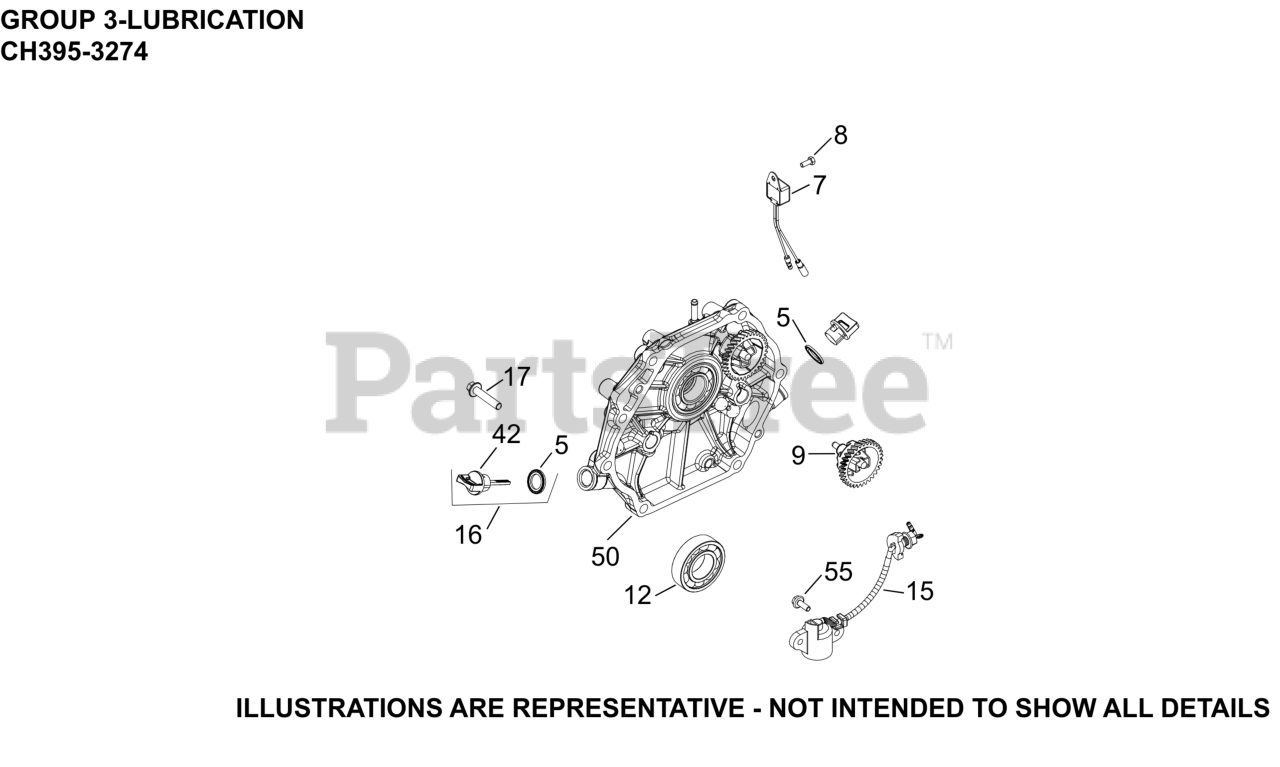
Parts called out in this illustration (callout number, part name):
5	SEAL, DIPSTICK
7	CONTROL, OIL ALERT UNIT
8	SCREW, HEX/PHILLIPS M5
9	GOVERNOR, ASSEMBLY
12	BEARING, CRANKSHAFT
15	SWITCH, OIL SENSOR ASSEMBLY
16	DIPSTICK ASSEMBLY
17	SCREW, CLOSURE PLATE
42	DIPSTICK - USE 17 038 08-S
50	PLATE, CLOSURE & BEARING
55	SCREW, M6 X 16
